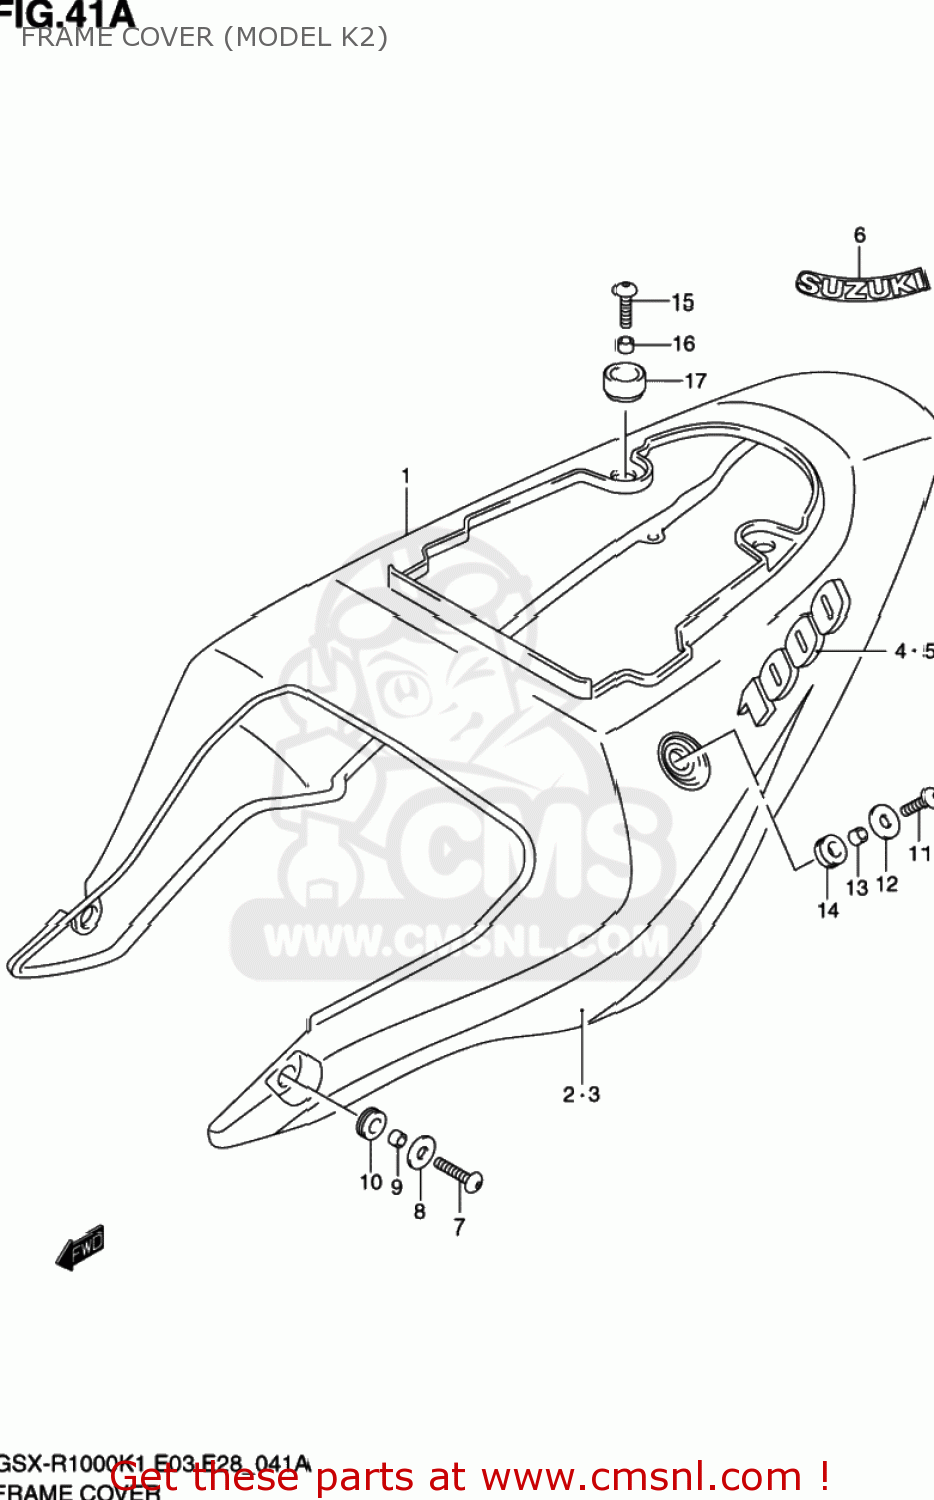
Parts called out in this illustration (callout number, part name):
1	COVER ASSY,FRAME
2	TAPE,FRAME COVER,R(BLUE)
3	TAPE,FRAME COVER,L(BLUE)
4	EMBLEM,1000
5	EMBLEM,1000
6	EMBLEM,FRAME COVER
7	SCREW(6X30)
8	WASHER(6.5X20X2)
9	SPACER(6.5X10X7)
10	CUSHION,FRAME COVER FR
11	SCREW(6X25)
12	WASHER(6.5X20X2)
13	SPACER(6.5X10X7)
14	CUSHION,FRAME COVER SIDE
15	SCREW(6X25)
16	SPACER(6.5X10X9.4)
17	CUSHION
